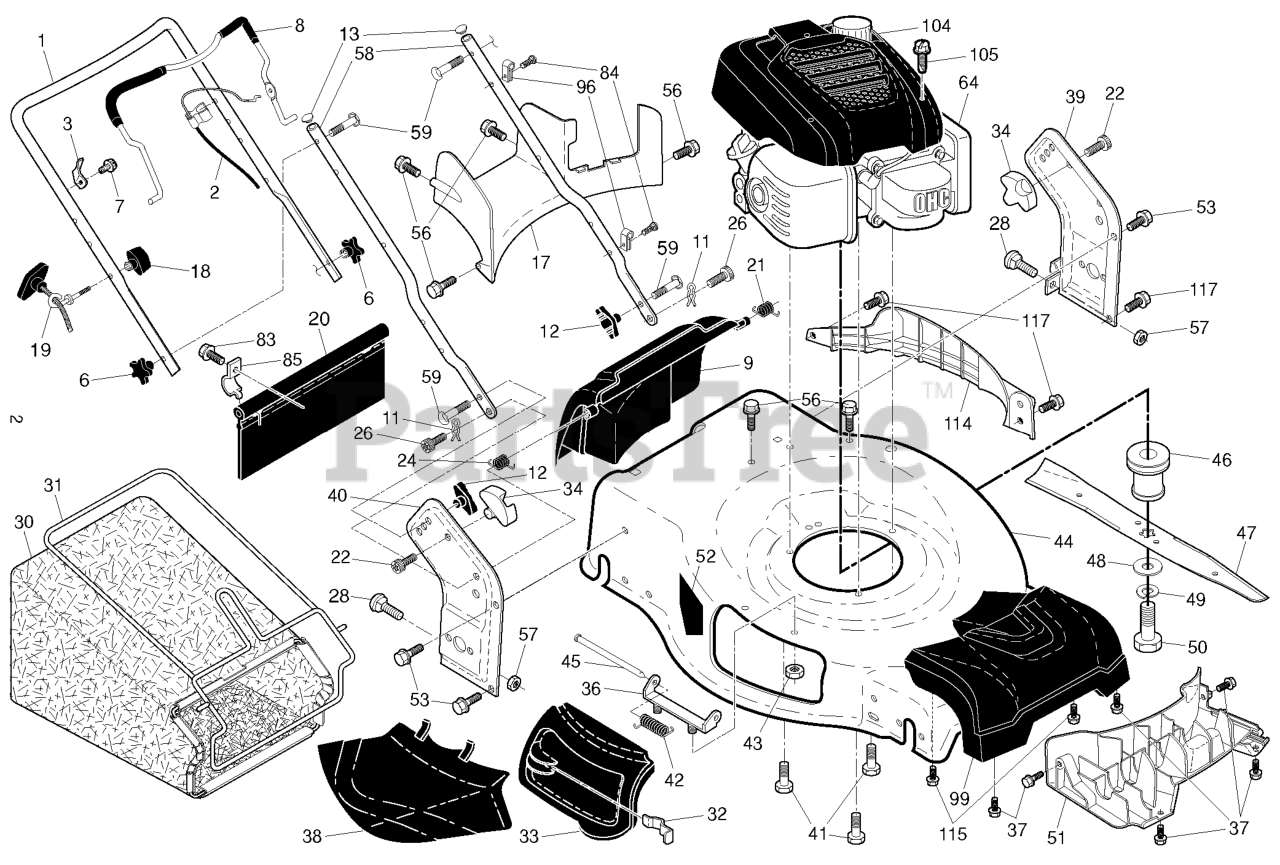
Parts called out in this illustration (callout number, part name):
1	HANDLE.UPPER.3.POS.BS.AW2.GREY
2	CABLE.MZR.50.SNAP-IN
3	BRACKET.UPSTOP.RT
6	KNOB.HANDLE.PLASTIC.STAR.BLACK
8	BAIL.OVER.MOLD.ERGO.MZR.ORANGE
9	DOOR.REAR.ASM.22+.HUSQ.FG/RGD
11	COTTER.HAIRPIN.DOOR/HANDLE.PIV
12	KNOB, DEFLECTOR
13	PLUG.PLASTIC.7/8".14-20.GAUGE
17	BAFFLE.REAR.22+RGD.AWD.PLASTIC
18	T-KNOB.NEW ROPE GUIDE
19	GUIDE.ROPE.BLK.ZINC.CHROM
20	SKIRT.REAR.22PLUS.RGD.LW(2 2MC
21	SPRING.LH.BLACK
22	SCREW.PAN.HEAD.#10
24	SPRING.RH.GRAY
26	SCREW,DOOR/HANDLE.PIVOT
28	BOLT.CARRIAGE.LN.5/16-18X.5/8
30	GBAG.BA85028EM.NOFRAME.GRY/SLV
31	FRAME.GBAG.22+.BLK
32	LATCH.DOOR.ZINC
33	DOOR.MULCH.22 PLUS.HUSQ.GREY
34	BRACKET.GRASSBAG.ATTACHING.BLK
36	BRACKET.ASM.HINGE.21.FWGD.
37	SCREW.HI-LO. 5/16 X 1.00
38	DEFLECTOR.CLIPPING.22.BLACK
39	BRACKET.ASM.HANDLE.LT.22+.GREY
40	BRACKET.ASM.HANDLE.RT.22+.GREY
41	BOLT 3/8-16X1-1/8
42	SPRING.TORSION
43	NUT.HEX.FLANGE.1/4
44	HOUSING.22+.AWD.MC.WO.ORANGE.T
45	ROD.HINGE.21
46	ADAPTER.BLADE.25MM.3MPH
47	BLADE.22+4N1.2PIN.5STAR.(P07)
48	WASHER,HARDEN
49	LOCKWASHER
50	SCREW, HEX HD 3/8-24 X 1-3/8
51	BAFFLE.FRONT.22+PLASTIC.(2 2)
52	DANGER DECAL
53	BOLT.5/16HEX.WHS.HD
56	SCREW.HX.13X.750
57	NUT.FLANGE.5/16
58	HANDLE.LOWER.22+BT.2PC.GRY
59	BOLT, HANDLE 5/16-18X1.75
83	TAPPING SCREW
84	FASTENER.PUSH.O.250X0.783
85	BRACKET.SKIRT.22+.BZP
96	CLIP.CABLE.BLK
99	COVER.ASM.FRONT.SHROUD.HUS.AWD
104	SHROUD.ASM.HONDA.HUSQVARNA
105	SCREW.SHROUD.HONDA
114	RP BUMPER.HUSQVARNA
115	SCREW.SHOULDER.5/16X1.375
117	BOLT.HEX.HD.WASHER.5/16-18X.75
